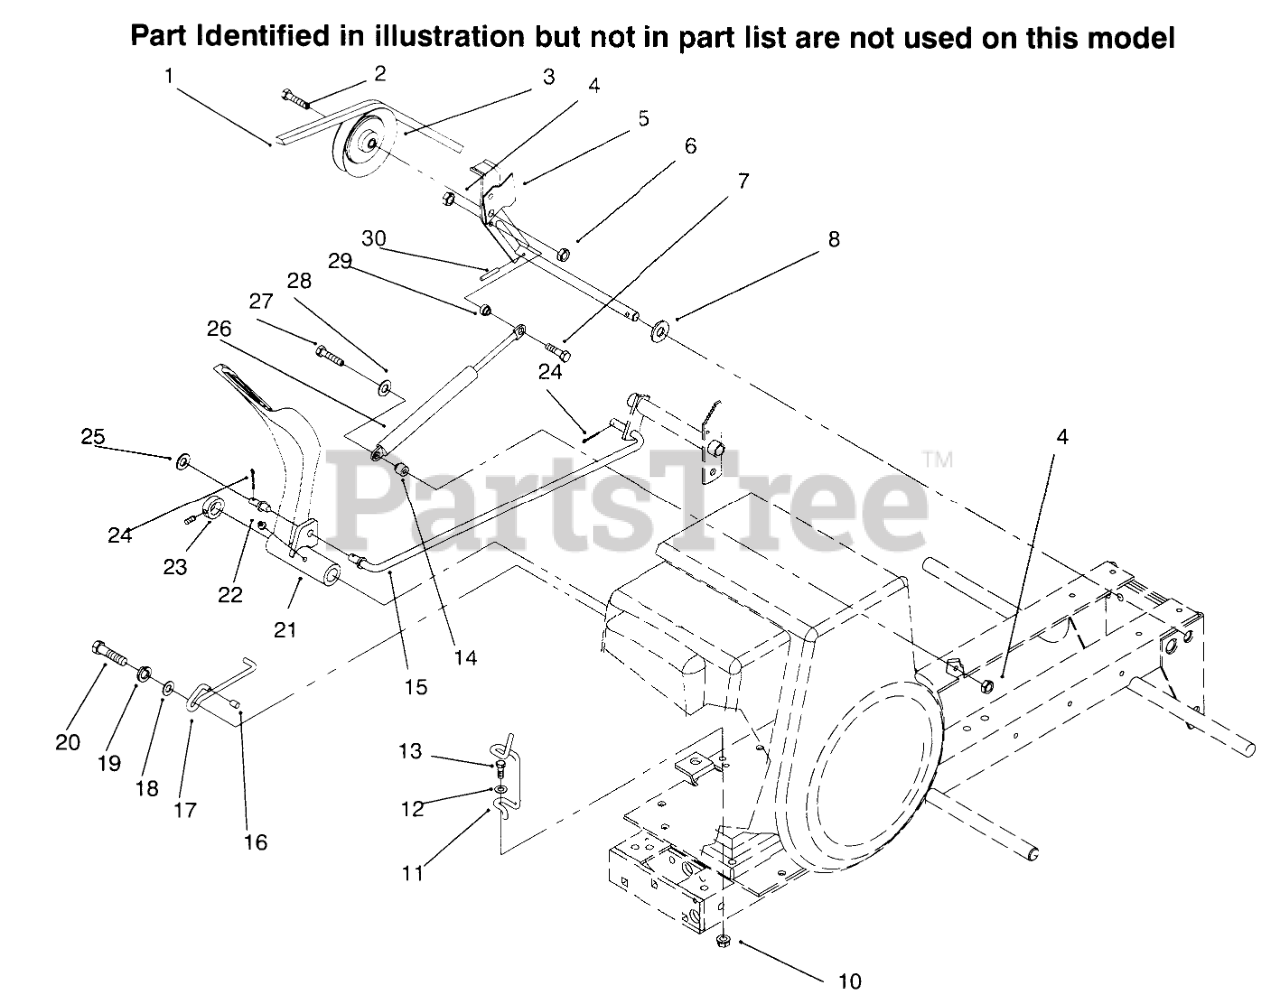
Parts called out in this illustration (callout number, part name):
1	BELT-V IN
2	BOLT-SPECIAL HEX
3	PULLEY-IDLER
4	NUT-LOCK, NI
5	Arm-Clutch Idler
6	NUT-HEX
7	Capscrew
8	SHIM-WASHER
14	SPACER-SHOULDER-.400
15	ROD-BRAKE
17	GUIDE BELT
18	WASHER-FLAT
19	WASHER-LOCK
20	SCREW-HH
21	Pedal-Brake
22	FITTING-GREASE
23	COLLAR
24	PIN-COTTER
25	WASHER-NYLON
26	ASS'Y-GAS SPRING
27	SCREW-HH
28	WASHER-FLAT
29	SPACER-SHOULDER-.200
30	PIN-SPIROL
